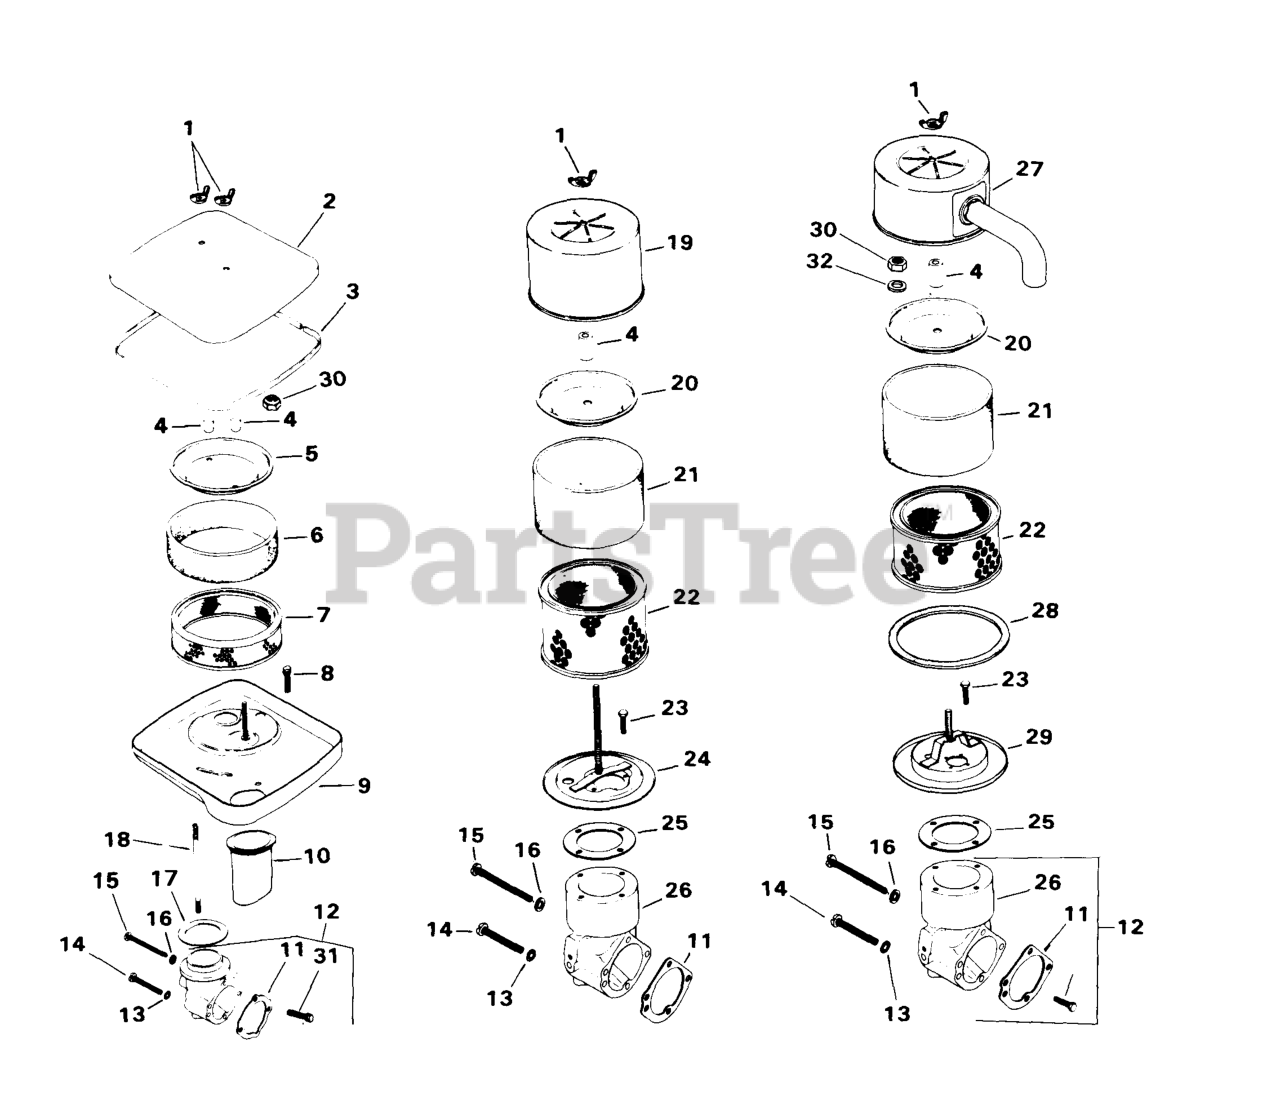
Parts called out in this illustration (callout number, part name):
1	NUT, WING 1/4-20 USE 25 100 15-S
2	COVER - (#DSC)
3	SEAL, AIR CLEANER - (#DSC)
4	SEAL, BREATHER
8	SCREW, WSH HD TAP 1/4-20X7/16" USE 25 086 106-S
9	BASE - (#DSC)
11	GASKET, AIR CLEANER ELBOW
12	KIT, ELBOW - DISCONTINUED
13	WASHER, INT TOOTH LOCK #10
14	SCREW, SLT PAN HD 10-32X1 1/2" USE 25 086 63-S
15	SCREW, SLT PAN HD 10-32X2 1/4"
16	WASHER, FLAT 3/16"
18	STUD,1/4-20x4-3/4" USE 25 072 10-S
31	SCREW, WSH HD TAP 1/4-20X3/4" USE 25 086 100-S
